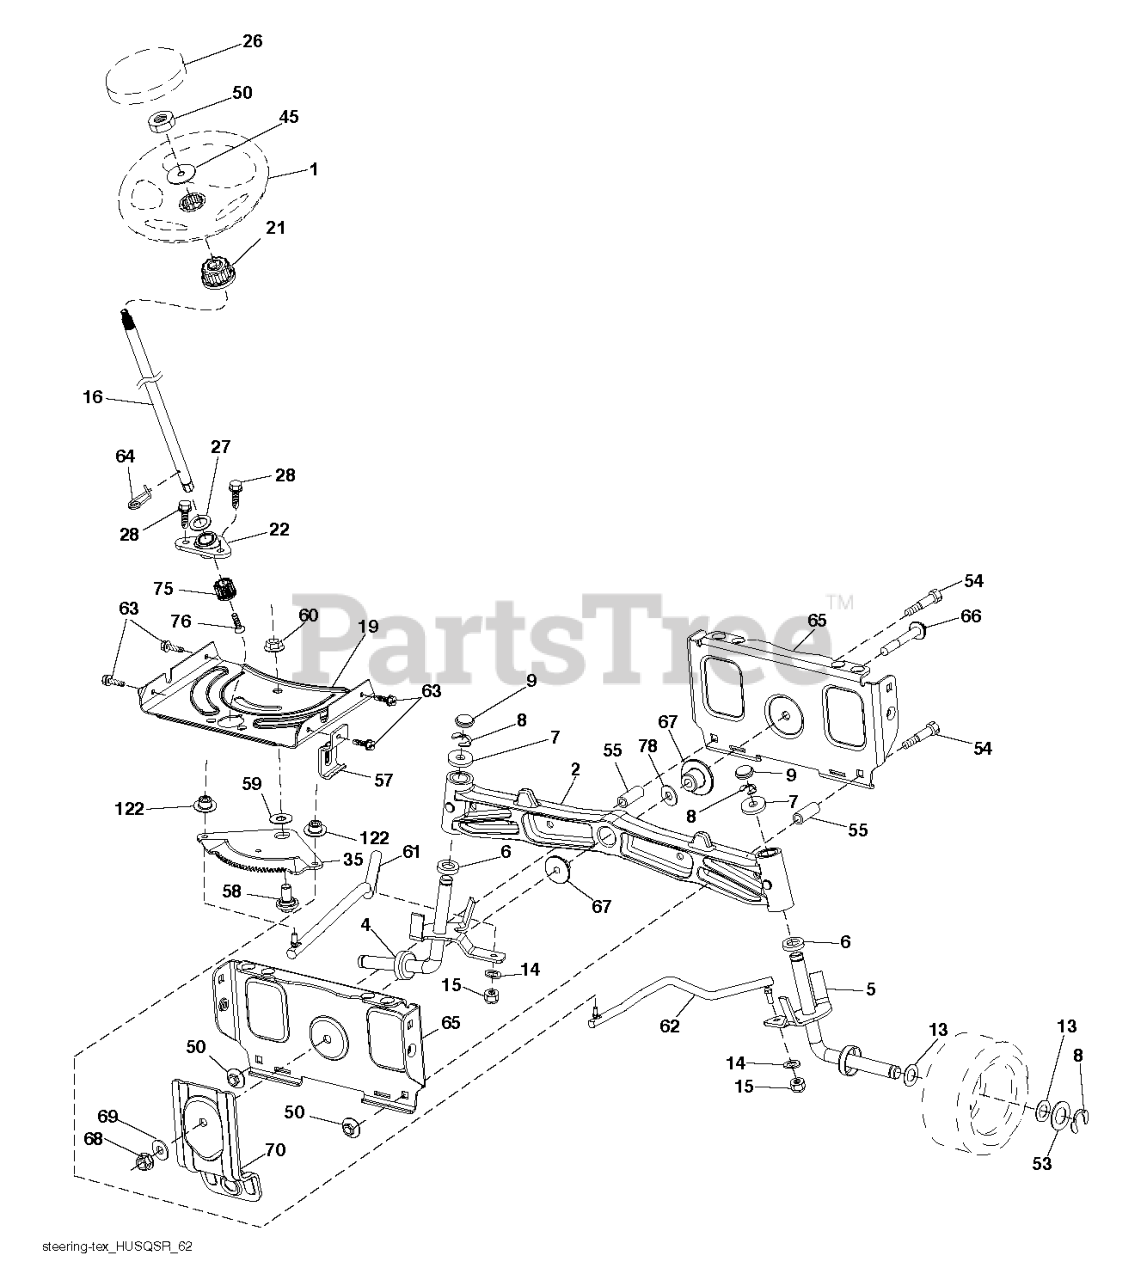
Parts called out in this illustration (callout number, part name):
1	WHEEL.STEER.HUSQ.SR.498.OVMLD
2	AXLE.CAST.IRON
4	SPINDLE.WELDED.LH.16"TEX
5	SPINDLE.WELDED.RH.16"TEX
6	THRUST WASHER
9	CAP.SPINDLE.BLACK
14	WASHER, LOCK 3/8
15	NUT CROWNLOCK 3/8-24
16	SHAFT, STEERING
19	PLATE.STEER.DDL.NLT/NG
21	ADAPTER, WHEEL STNG..
22	STEERING.SUPT.LOWER.
26	INSERT.CAP.WHL.STRG.HUSQ.PREM
28	SCREW, 3/8-16X3/4
35	GEAR.SECTOR.PLATE.DDL.
45	WASHER 9/16"ID, 2 3/8"OD
50	NUT LOCK FLG 3/8-16 UNC
51	NUT.HEX.1/2-20
53	WASHER.HARDENED
55	SPACER.BRACE.AXLE
57	BRKT.UPSTOP.GT/LT.TEX
58	BOLT.SHOULDER.SECTOR.P
59	WASHER.THURST.SECTOR.S
60	NUT FLANGE LOCK 5/8-11
61	DRAGLINK.LH.BALLSTUD.D
62	DRAGLINK.RH.BALLSTUD.D
63	SCREW
64	RETAINER.CLIP.SPRING.S
65	BRACE.AXLE.FRONT.NLT/N
66	BOLT HEX FGHD 7/16-14 X 3 SERR
67	BUSHING.PM.FRONT AXLE
68	NUT.LOCK.FLANGE.7/16
69	WASHER.1.5X.505X.118
70	BRKT.DECK.SUSPENSION.F
78	THRUST WASHER
122	CAP.GEAR.SECTOR.TEX
